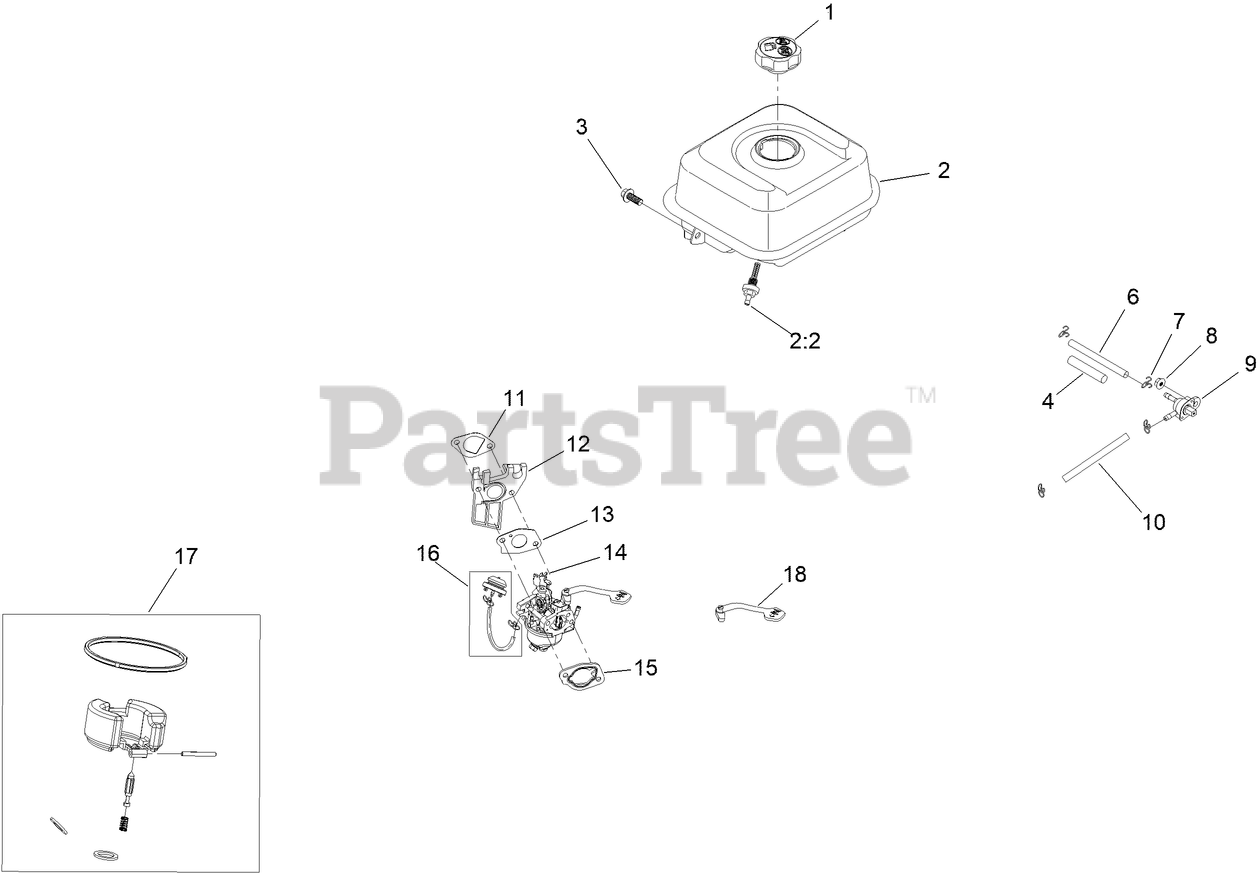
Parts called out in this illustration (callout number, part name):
1	CAP-FUEL
2	FUEL TANK AND FILTER ASM
2:2	FILTER-FUEL
3	SCREW-HHF
4	SLEEVE-ABRASION
6	HOSE-FUEL
7	CLIP-HOSE
8	NUT-FLANGE
9	VALVE-FUEL
10	HOSE-FUEL
11	GASKET-CARBURETOR
12	INSULATOR-CARBURETOR
13	GASKET-CARBURETOR
14	CARBURETOR ASM
15	GASKET-CARBURETOR
16	PRIMER KIT
17	INTERNAL CARB SERVICE KIT
18	LEVER-CHOKE
